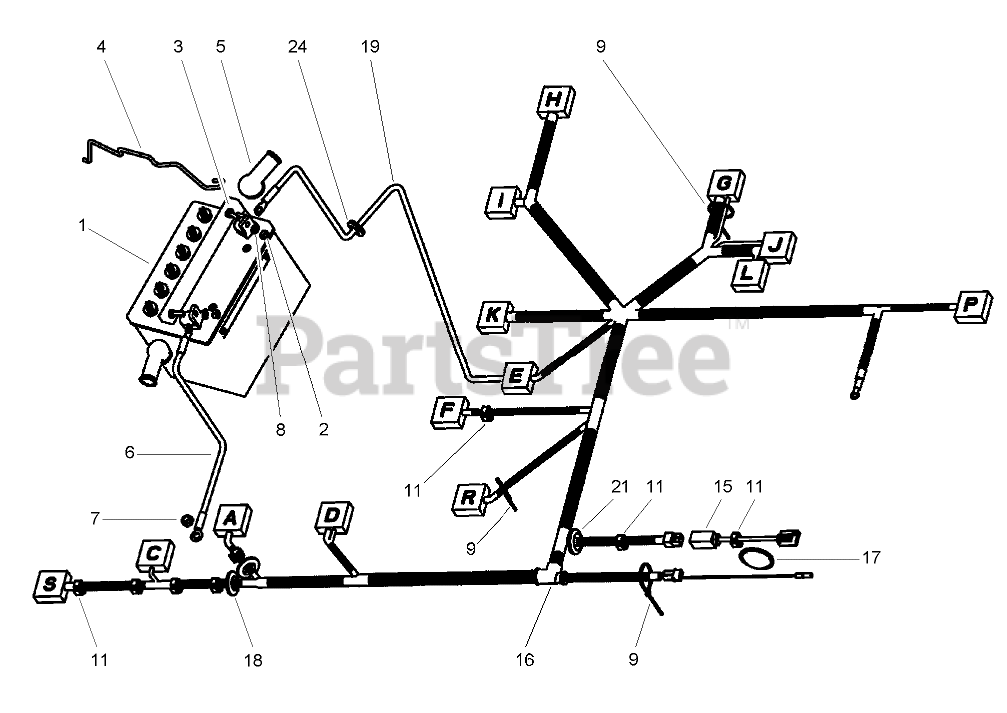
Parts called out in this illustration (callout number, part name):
1	BATTERY-12V
2	NUT-HEX
3	SCREW-HH
4	CLAMP-BATTERY
5	BOOT-RUBBER
6	CABLE-BATTERY, Negative
7	NUT-LOCK, NI
8	WASHER-FLAT
9	TIE-CABLE
11	CLIP-SNAP
15	HARNESS-CLUTCH
16	HARNESS-WIRING
18	BUSHING
19	CABLE-BATTERY POSITIVE
21	BUSHING
24	GROMMET
